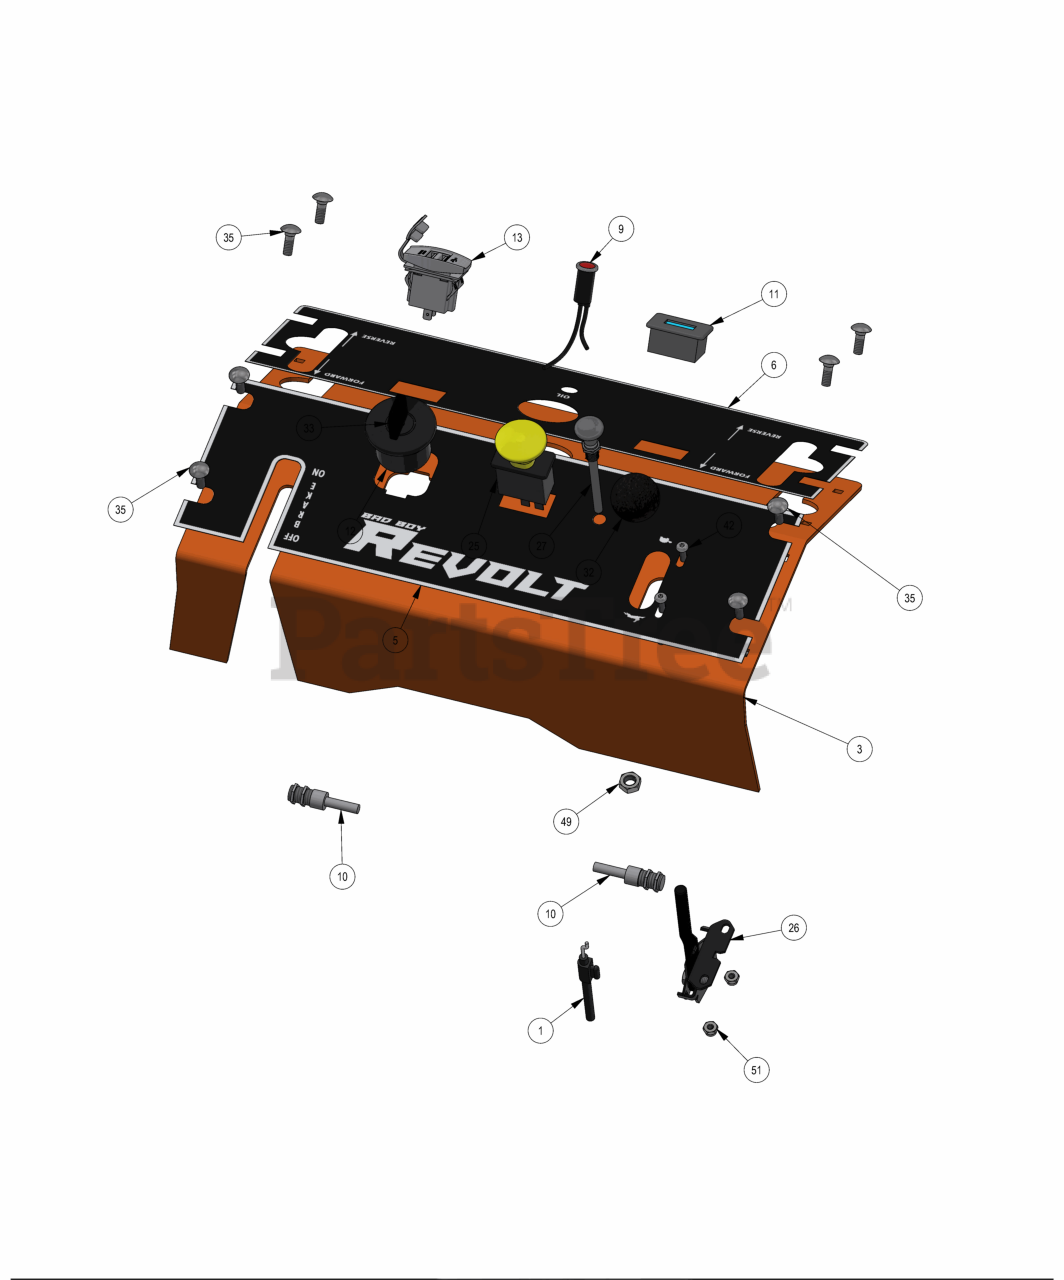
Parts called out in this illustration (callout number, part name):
1	Outlaw Throttle Cable
2	5/16-18 NYLON INSERT JAM LOCKNUT ZINC
3	36" Podium Front Panel Weldment 2020 Stand On
4	2020 36" Hydrotank Carrier Plate 2020 36" Stand On
5	36" Control Panel (lower) - Revolt
6	36" Control Panel (upper) - Revolt
7	2019 Stand On Brake Handle BLACK
8	36" Front Control Arm Stop Weldment 2020 36" Stand On
10	Safety Switch Harness
11	Tachometer
12	Ignition Switch
14	Magnet-Steering Arm-Stand ON
15	2019 Stand On Waterbottle Cage
16	2019 Stand On Control Grip
17	8507A13 McMaster Carr Plunger
18	Interstate FAYTX14 Battery
19	350ml Expansion Tank
20	Hydraulic Tank Cap
21	ZT/Maverick Hydro Tank Hose
22	3/8" Hose Clamp
23	1/2 Hose Clamp
24	Brake Cable
25	PTO Switch
26	Universal Throttle Head - 2012
28	2020 36 Stand On Drive Arm Pivot Bar
29	8-32 HEX M/S NUT ZINC
30	Safety Switch
31	Rubber Brake Grip-cZT/ZT 2013
32	Throttle Knob
33	Ignition Key
34	Brake Spring
35	1/4-20 X 3/4 CARRIAGE BOLT (GR.5) ZINC
36	1/4-20 NYL INSERT FLANGE LOCKNUT ZINC
37	3/8 FLAT WASHER USS (1" OD) ZINC
38	3/8 SPLIT LOCKWASHER ZINC
39	.390 ID X 1.12 OD X .125 THK FLAT WASHER NYLON
40	.390 ID X .750 OD X .062 THK FLAT WASHER NYLON
41	3/8-16 X 1 GR 5 Hex Bolts Zinc
42	10-24 X 5/8 BUTTON SOCKET CAP SCREW 18-8 STAINLESS STEEL
43	3/8-16 X 1-1/4 CARRIAGE BOLT ZINC
44	5/16-18 X 1-1/2 CARRIAGE BOLT ZINC
45	12-24 X 1/2 HEX WASHER UNLSOT F TCS ZINC
46	5/16-18 X 6 CARRIAGE BOLT (GR.5) ZINC
47	M6-1.0 X 16MM DIN 933 HEX TAP BOLT (CL 8.8) ZINC
48	5/16-18 HEX SERRATED FLANGE NUT HARD/ZINC
49	3/8-24 HEX NUT ZINC YELLOW
50	3/8-16 NYLON INSERT FLANGE LOCKNUT (GR.F) ZINC
51	10-24 NYLON INSERT LOCKNUT ZINC
52	5/16-18 X 1 CARRIAGE BOLT (GR.8) ZINC
53	5/16-18 NYLON INSERT FLANGE LOCKNUT ZINC
54	1/4" Vinyl Tubing, 46" Long
55	3/16 Vinyl Clamp
56	3/16" Vinyl Tubing, 55" Long
57	3/16" Vinyl Hose Clamp
58	2023 36-SD Stand On Drive Arm Actuator weldment_left
59	2023 36-SD Stand On Drive Arm Actuator weldment_right
60	2023 Stand on Battery Hold Down
61	Nylon 6 6 Sleeve Washer
62	2023 Podium Panel Left
63	2023 Podium Panel Right
64	MZ Kohler EPA Canister Assembly
65	Expandable Locking Grommets
66	2023 36''/SD Control Arm Stop Weldment_Rear
67	2023 36-SD Stand On Console Bracket Weldment
68	Adjustable handles ERX.30 B-10-24-C1
69	2023 Floor Board Rubber Bumper
70	2019 Revolt Push Rod Assembly
71	ACS Spacer 3/4x3/8x1/4
72	5/16-18 X 1-1/4 HEX C/S (GR.5) ZC
73	5/16 USS FLAT WASHER (7/8 OD) ZINC
74	5/16 SPLIT LOCKWASHER ZINC
75	5/16-18 X 1 HEX CAP SCREW (GR.5) ZINC
76	2023 36-SD Stand on Pad Plate
77	.360 ID Plastic Washer
78	Relay Block Cover Replacement Kit
80	36'' Revolt Seat Pad
